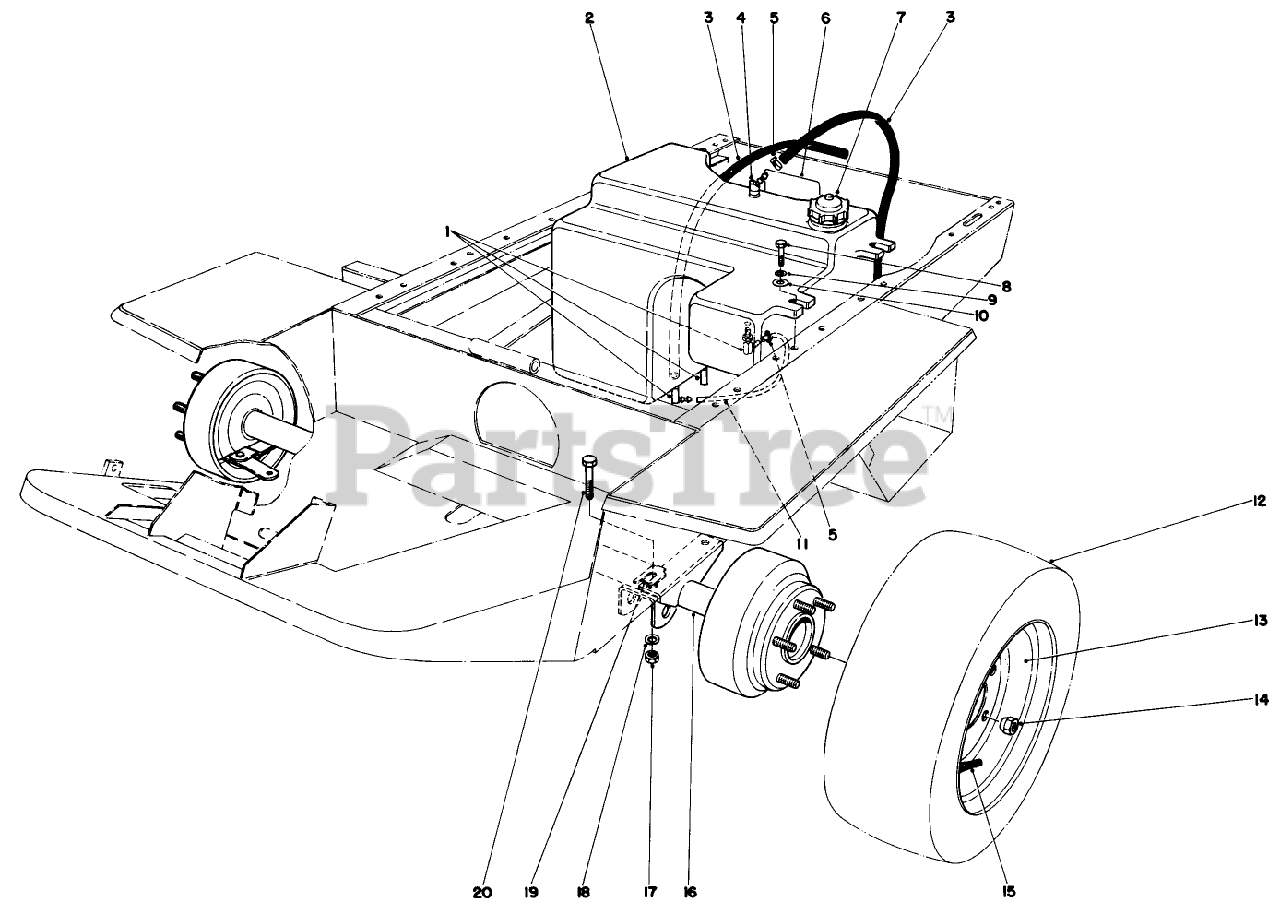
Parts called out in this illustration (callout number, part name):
2	GAS TANK
5	CLAMP-HOSE
6	DECAL-DANGER
8	SCREW-HH
9	WASHER-LOCK
10	WASHER
12	TIRE(20X8-10) 4-PLY
13	WHEEL ASM
14	NUT-WHEEL
17	NUT-HEX
18	SCREW-HH
19	SHIM-AXLE
20	SCREW-HH
